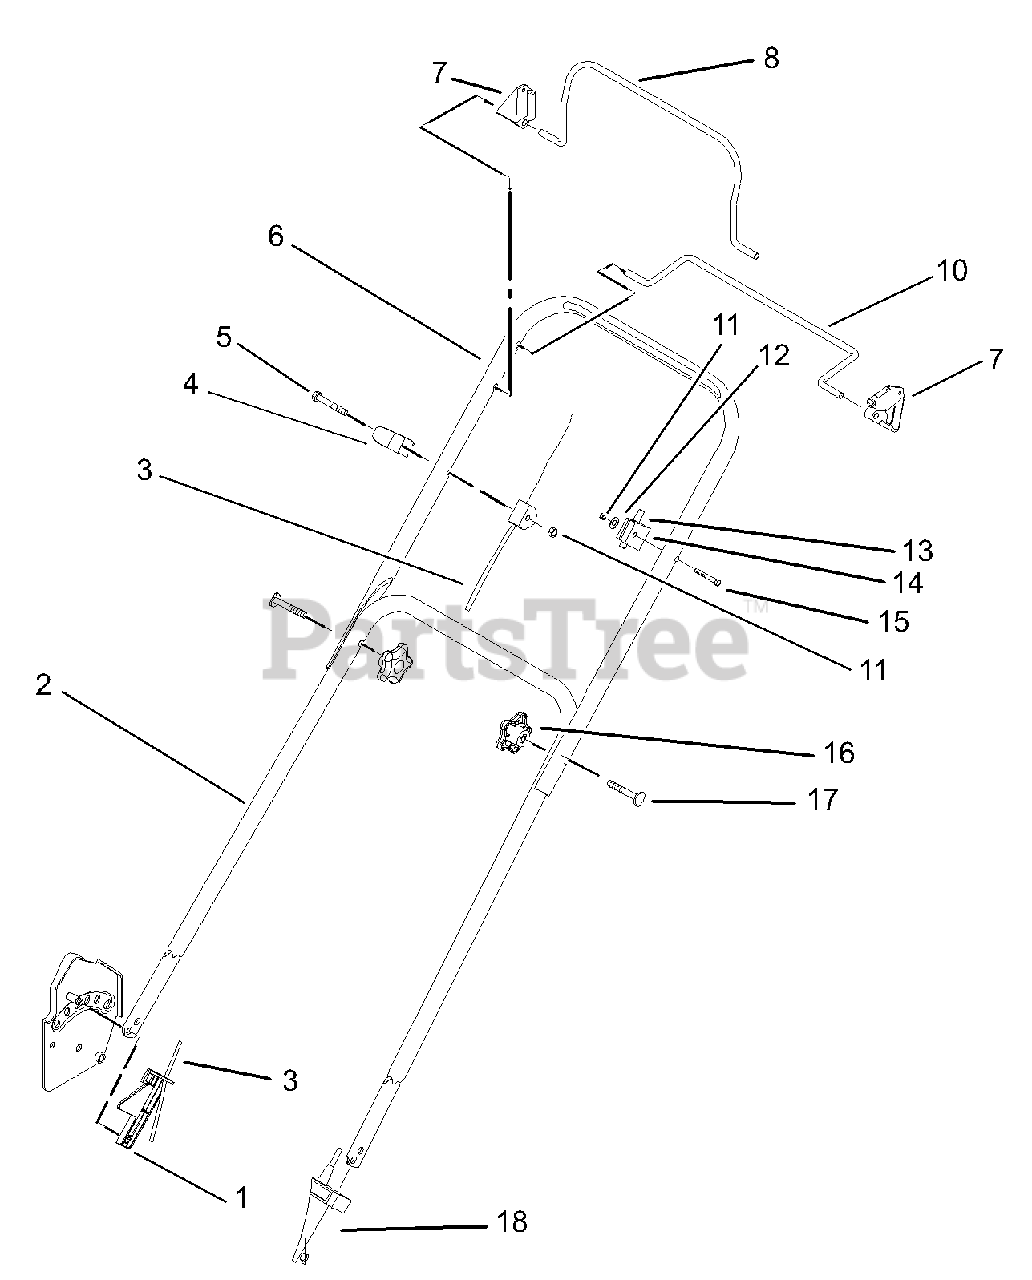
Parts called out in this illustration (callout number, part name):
1	Guard-Cable
2	Handle-Lower
3	Brake Cable ASM
4	Guide-Rope
5	Screw-HH
6	Handle-Upper
7	Stop-Pivot
8	Bail-Brake
10	Bail-Control
11	Nut-Lock, NI
12	Washer-Flat
13	Cable-Ground Speed
14	Anchor-Upper, Cable
15	Screw-Handle
16	Knob-Handle
18	Anchor-Cable
